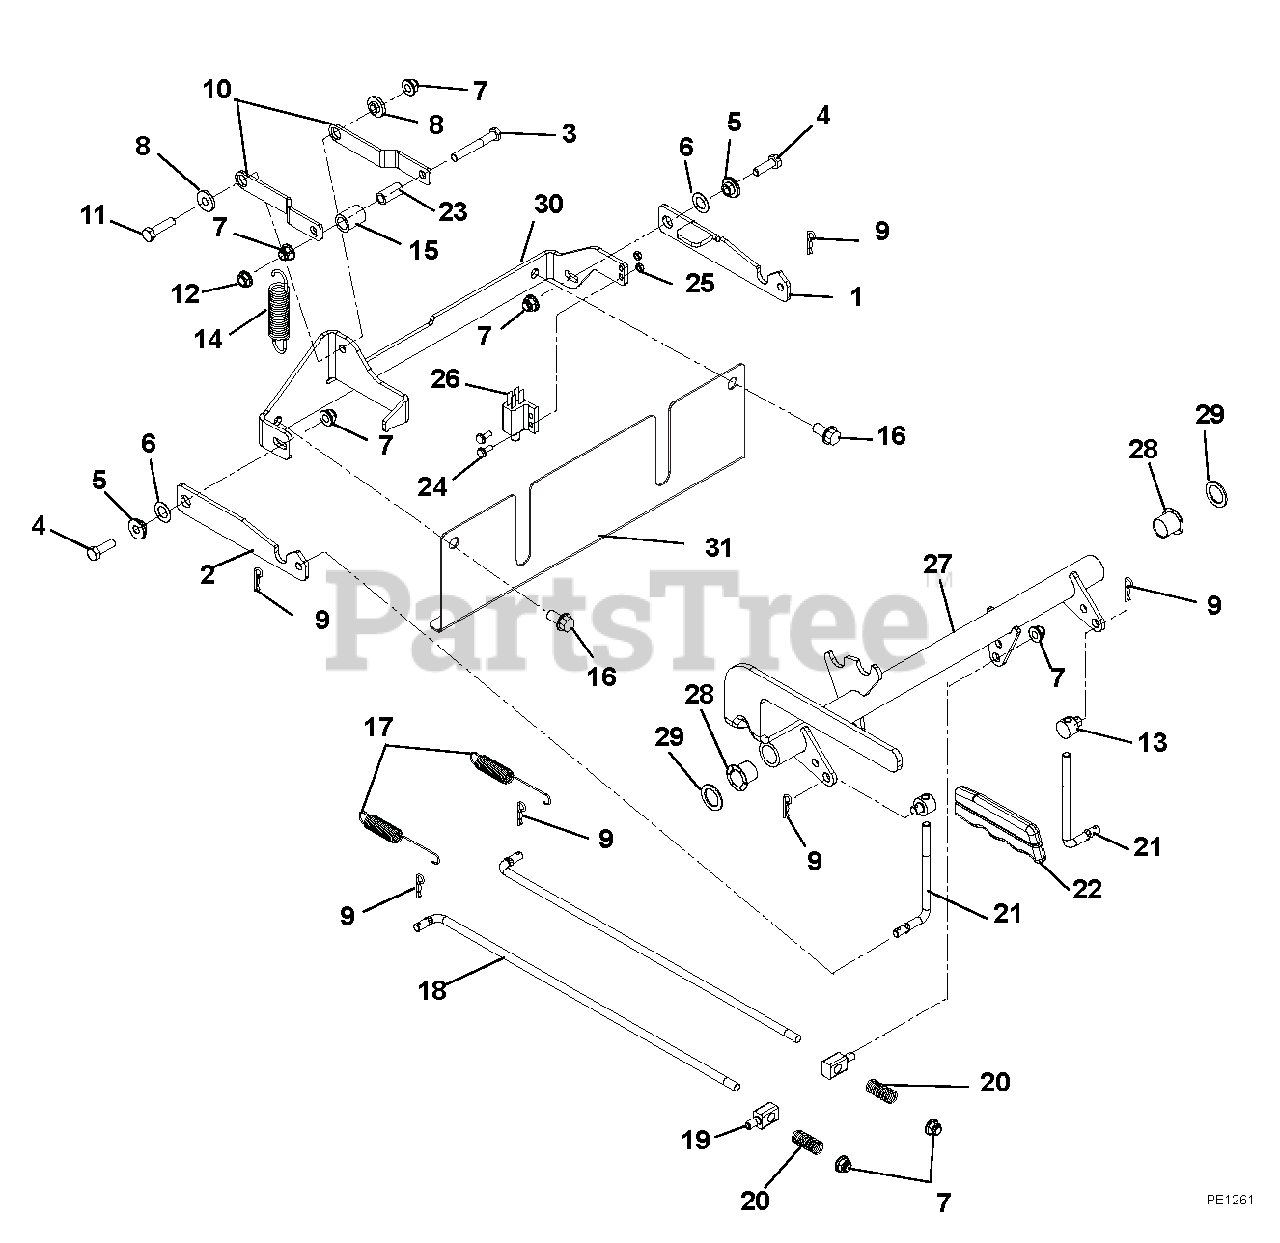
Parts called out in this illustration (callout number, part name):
1	LINK, BRAKE INTERLOCK
2	INTERLOCK, BRAKE
3	@BLT-HEX .31-18X2.25 GR5 YWZC
4	@BLT-HEX .31-18X1.00 GR5 YWZC
5	BSHG-FLG .32X.500X.344X.880
6	WSHR-FL-STL .505X.875X.024 YWZ
7	@NUT-LK-NYL-FLG .31-18 YWZC
8	BSHG, FLG .325X.499X.26X.88
9	PIN-HAIR INT .08X.18X1.18 YWZC
10	ARM, BRAKE CAM
11	@BLT-HEX .31-18X1.25 GR5 YWZC
12	@NUT-LK-TOP-FLG .31-18 YWZC
13	TRUNNION, BRAKE .31-18 UNC
14	SG-TENS .105X.812X3.88 WLD 15
15	ROLLER, CAM LOCK
16	@SCR-TAP .38-16X.75 HWH TR YWZ
17	SG-TENS .056X.60X4.40
18	ROD, PARK BRAKE
19	PIN, PIVOT/TRUNNION
20	SPRING, COMPRESSION
21	LINK, INTERLOCK BRAKE
22	GRIP, PARKING BRAKE (YELLOW)
23	BSHG, SPCR .330X.500X1.01 PM
24	@SCR-MCH 10-24X.50 HWH YWZC
25	@NUT-LK-NYL 10-24 W/INSRT YWZC
26	SWITCH- DOUBLE POLE N.O./N.O.
27	SHAFT, BRAKE
28	BUSHING, IGLIDE CLIP
29	WSHR-FL-STL.754X1.125X.062YWZC
30	BRKT, BRAKE MTG
31	BRKT, LOWER FINGER GUARD - XL
